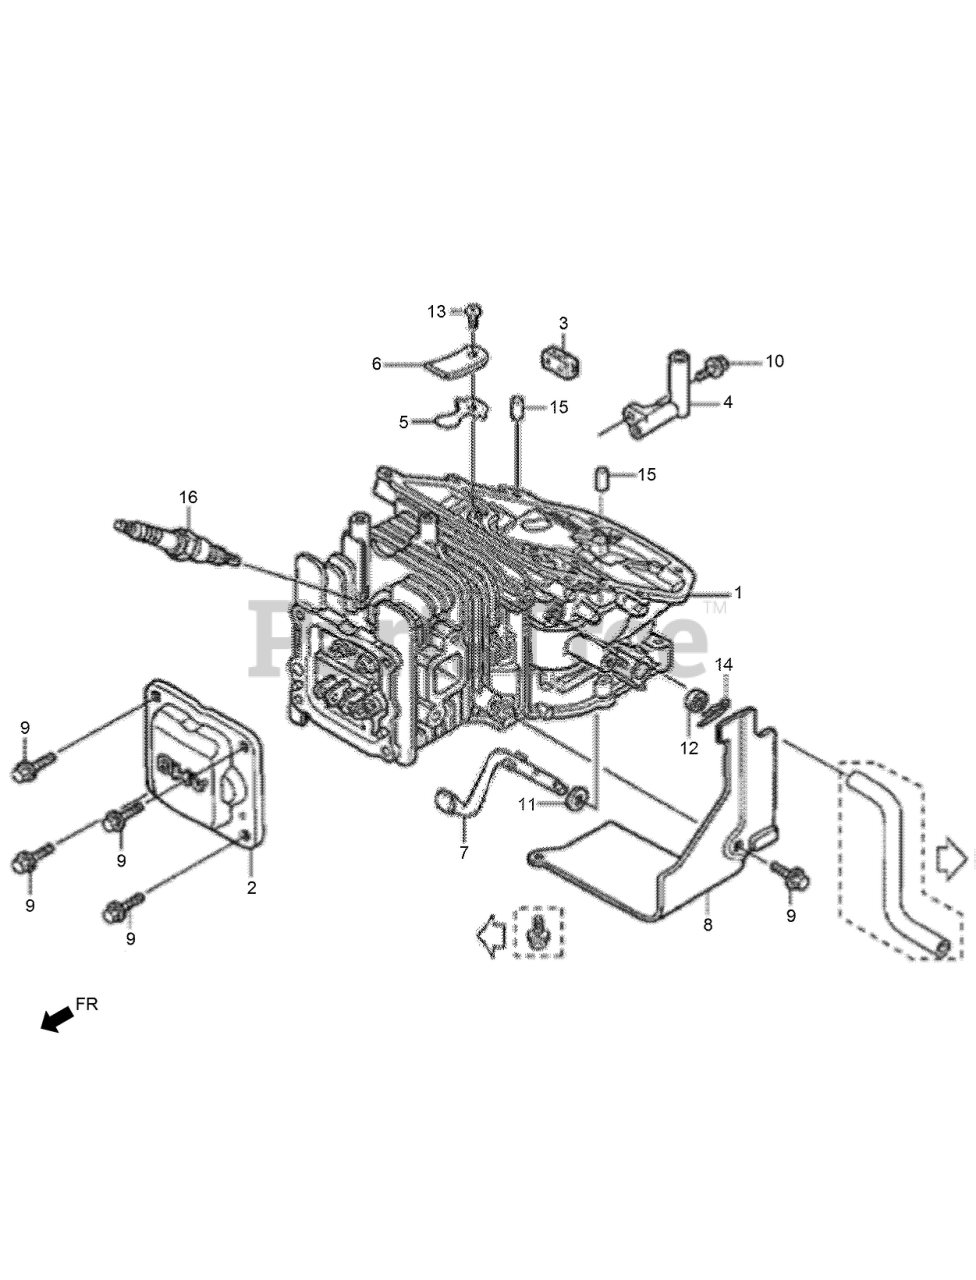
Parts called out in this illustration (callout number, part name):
1	CYLINDER BARREL ASM
2	COVER-HEAD
3	FILTER-BREATHER
4	PIPE-BREATHER
5	VALVE-OIL OUTLET
6	PLATE-STOPPER
7	SHAFT-GOVERNOR ARM
8	SHROUD
9	BOLT-FLANGE-5X12
10	BOLT-4X10
11	WASHER-5.2X9
12	ROLLER-6X14.8
13	OIL SEAL-5X11X5
14	SCREW-PAN-3X5
15	PIN-LOCK-6MM
16	SPARKPLUG (U16FSR-UB)
16	SPARKPLUG (CR4HSB)
